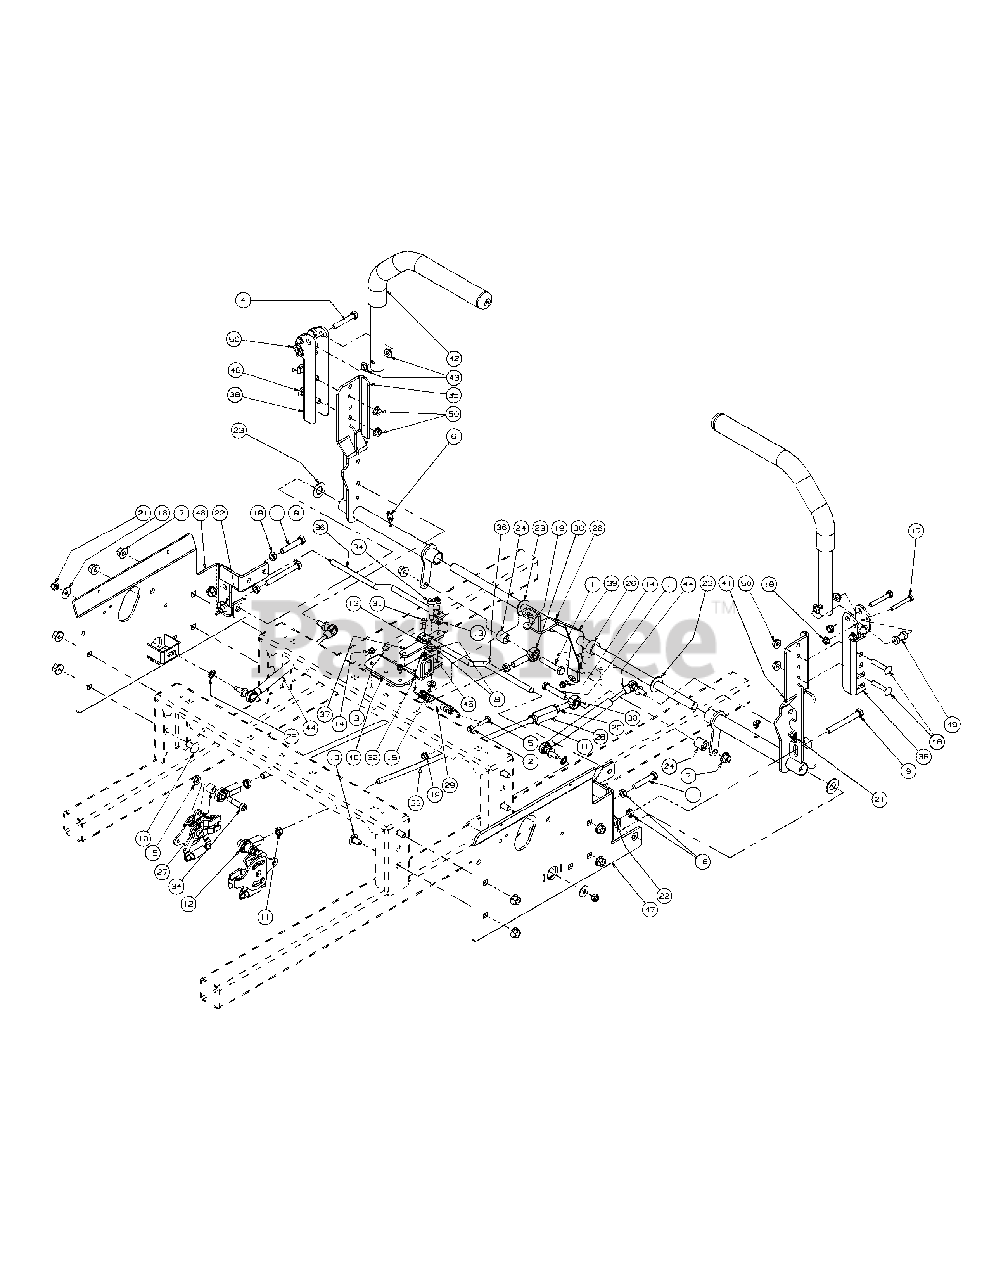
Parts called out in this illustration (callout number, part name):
1	Hex Cap Screw, 3/8-16 x 2.00
2	Hex Nut, 1/4-20
3	Hex Cap Screw, 1/4-20, .75
4	Hex Cap Screw, 5/16-18 x 2.00
5	HHCS, 1/4-20 x 1.00
6	Grease Fitting, 1/4-28, 45 degree
7	Hex Nut, 3/8-16, Lock Flange
8	Washer, 3/8, SS
9	Hex Cap Screw, 3/8-16 x 3.50
10	Carriage Bolt, 3/8-16 x .75
11	Hex Jam Nut, 3/8-24
12	B/Joint, 3/8-24, Right Hand Female
13	Flat Washer, 1.4 x .630 x .0515
14	Screw, TT, 1/4-20, 0.5, Hex Index Washer
15	Nut, Lock, HexFlange, 5/16-18
16	Belle Washer, .325 x .930 x .045
17	Hex Cap Screw, 1/4-20 x 2.00
18	Nut, 3/8-16, Jam
19	Hex Flange Lock Nut, 1/4-20
20	Nut, 3/8-24, Jam, LH Third
21	Nut, Hex, Center Lock, M8
22	U-Nut, 3/8-16, .75
23	Flat Washer, 5/8 Nylon
24	Spacer, .385 ID x .75 OD x .875
25	External Washer, 3/8
26	Shaft Collar
27	Spacer, .625 OD x .385 ID x 1/2
28	Turnbuckle
29	Extension Spring, .53 OD x 4.75
30	B/Joint, 3/8-24, Left Hand Female
31	Shoulder Bolt, 1/4 x 1/4
32	Nut w/ Star Washer, 10-24
33	Control Rod, 3/8 x 17.312
34	Screw, Shoulder Control Rod
36	Brake/Control Rod
37	Lapbar Control Arm
38	Lapbar Pivot Bracket
39	Lapbar Control Shaft Assembly
40	Lapbar/Brake Control Mounting Bracket
42	Lapbar Assembly includes:
42	Control Handle Pivot Tube
42	Grip, 1.0
43	Bushing, .310 x .172 x .688 x .06
44	Cylinder Return to Neutral
45	Spacer, .405 ID x 1.0 OD x .72
46	Side Panel, Control, Left
47	Side Panel, Control, Right
48	Carriage Bolt, 5/16-18 x 1.75
49	Spacer, .251 ID x .38 OD x 1.13 LG
50	Nut, Lock, HexFlange, 5/16-18
